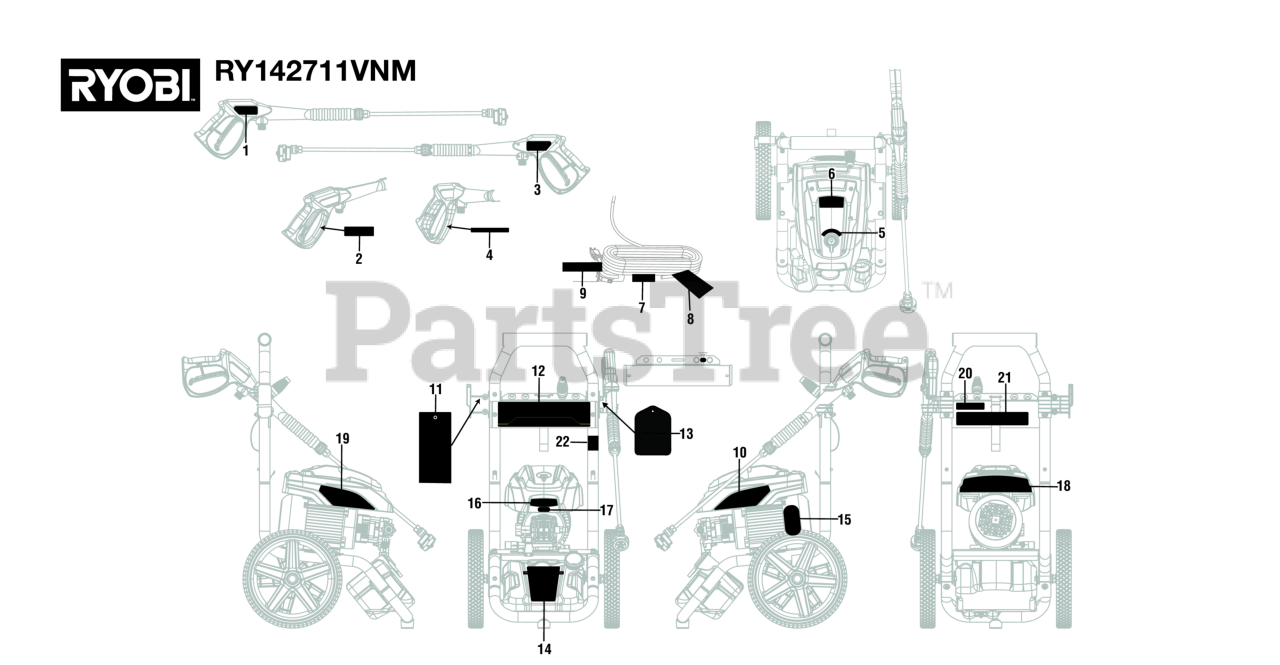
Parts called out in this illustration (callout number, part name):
1	Clutch Cover Label
2	Label (Trigger Handle Warning, French & Spanish)
3	Trigger Handle Warning Label (English)
4	Trigger Handle Rating Label
5	On / Off Label
6	High Performance Motor Label
7	Power Cord Label
8	Cordwrap Warning Label
9	Outlet Cord Wrap Label
10	Danger Icon Label
11	Danger Hangtag (Spanish)
12	Performance Label
13	Nozzle Hangtag
14	Detergent Tank Label
15	Data Label
16	Brushless Label
17	Logo Standard
18	Regulatory Danger Label
19	Danger Icon Label
20	Inquires Label (Ryobi)
21	Quick Start Label
